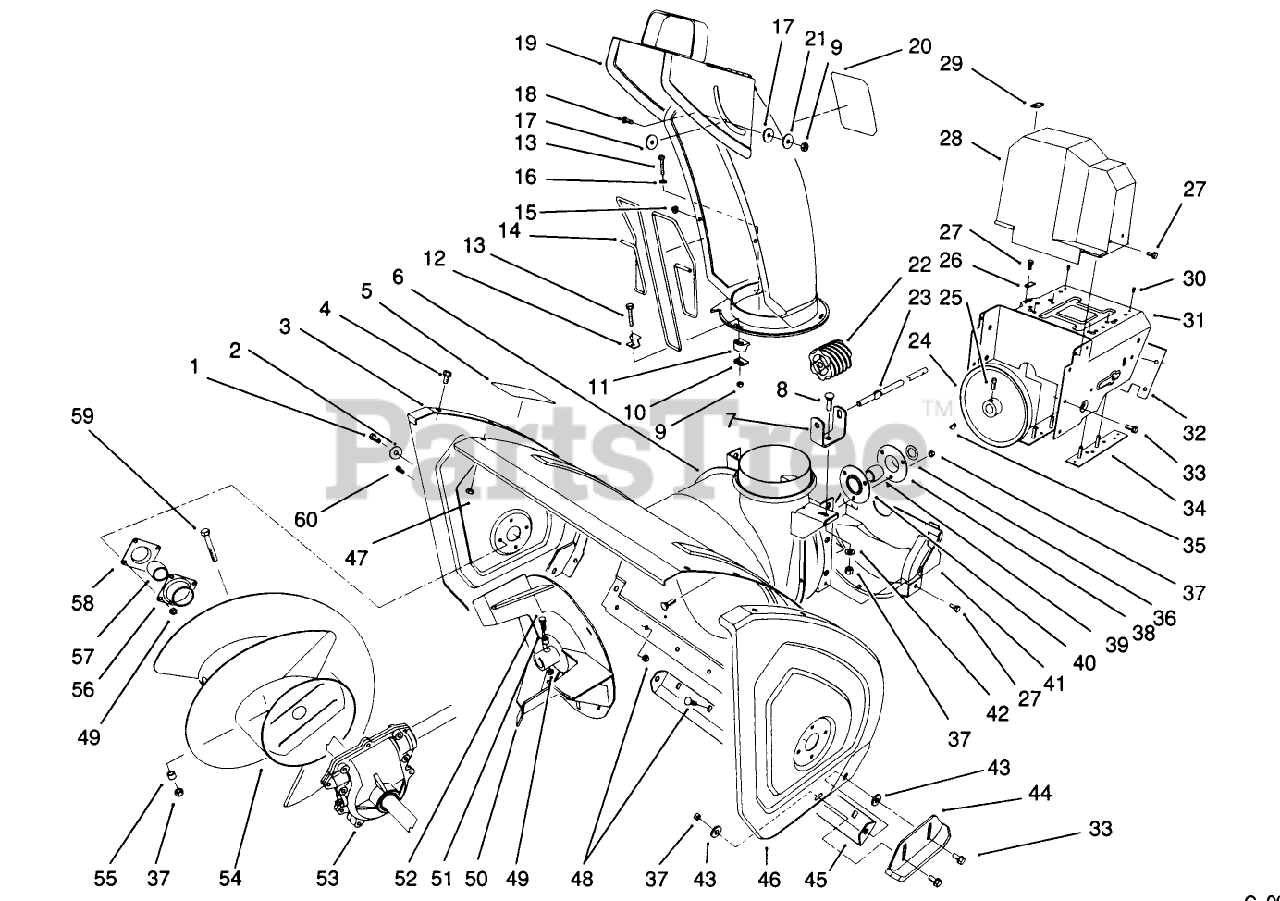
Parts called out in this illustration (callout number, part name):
1	SCREW-HH
2	WASHER
4	SCREW-HHF
7	BRACKET-WORM, CHUTE
8	BOLT-CARR
9	NUT-LOCK, NI
10	PLATE-RETAINER, CHUTE
11	RETAINER-CHUTE
12	CLIP-GUARD, CHUTE
13	SCREW-HSH
14	GUARD-CHUTE
15	NUT-PUSH
16	WASHER-FLAT
17	WASHER-PLASTIC
21	WASHER-FLAT
22	GEAR-WORM
23	ROD-CHUTE, LOWER
25	SCREW-SET, SQH
26	RETAINER-CABLE
27	SCREW-HWH
28	COVER-BELT, UPPER
29	COVER-CABLE
30	RIVET-POP
33	SCREW-HHF
35	KEY-WOODRUFF
36	WASHER-THRUST
37	NUT-LOCK, NI
38	Flange-Bearing (Rear)
39	BEARING-BALL
40	Flange-Bearing (Front)
42	WASHER-PLAIN
43	WASHER
47	NUT-LOCK, NI
48	SCREW-CARR
49	NUT-LOCK, NI
51	SPACER
52	SCREW-HHF
53	28IN AUGER GEARCASE ASM
54	R/H 28"AUGER WA *B
55	SPACER-HUB, AUGER
56	BEARING-FLANGE, FRONT
57	BEARING
58	BEARING-FLANGE, REAR
60	SCREW-HH
